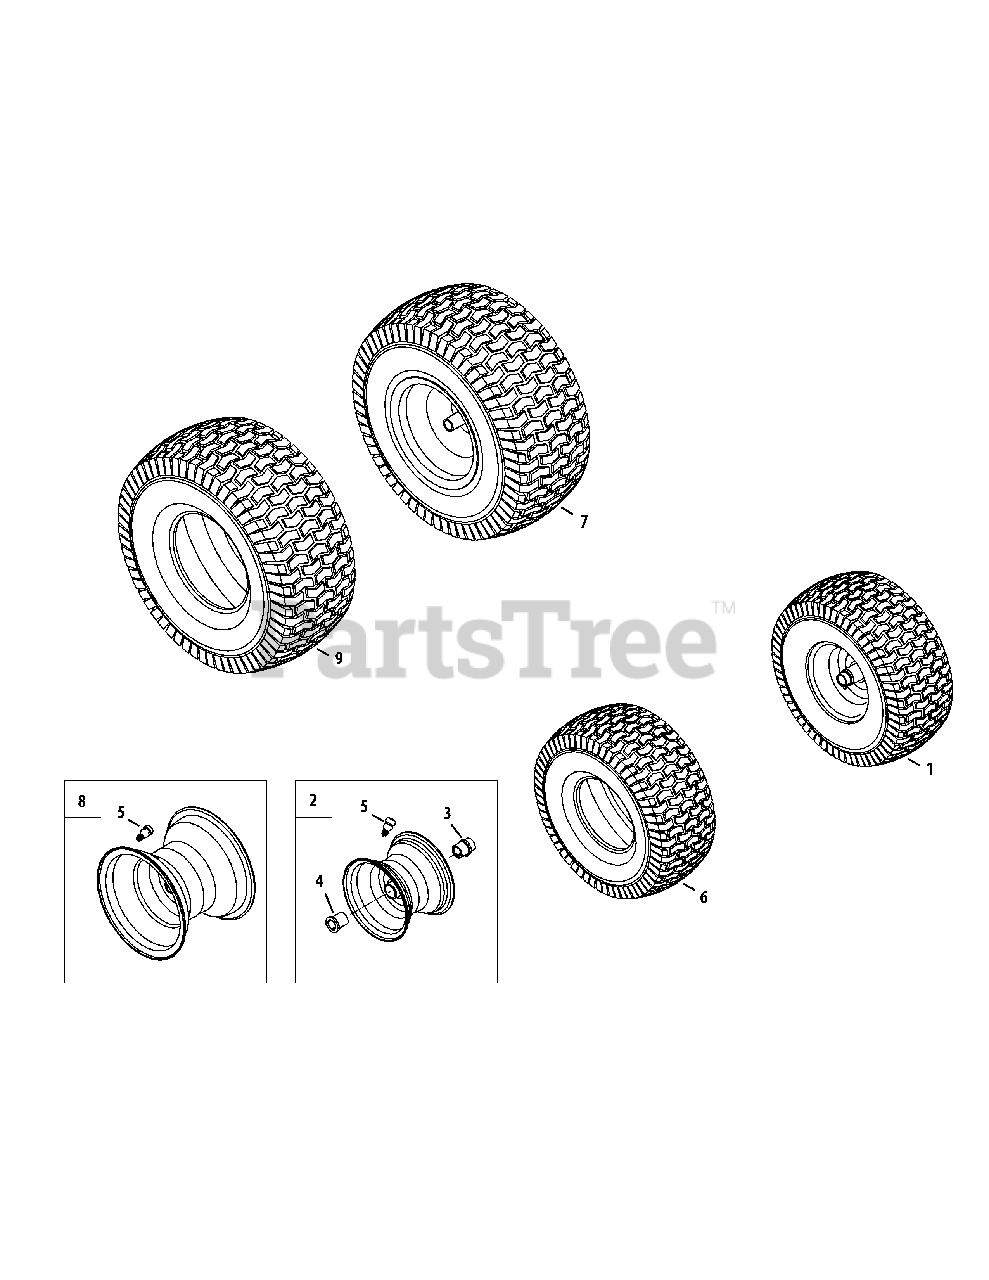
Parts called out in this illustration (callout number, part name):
1	Wheel Ass’y, Complete, 15 x 6 x 6
2	Rim Ass’y, 6.0 x 4.5, Flange Bearings
3	Bearing, Flange, .760 ID w/ Fitting
4	Bearing, Flange, .760 x 1.00 x 1.20
5	Valve, Tubeless Air
6	Tire, 15 x 6 x 6 Sq Shoulder
7	Wheel, Complete, 20 x 8 x 8
8	Rim Ass’y, 8.0 x 7.0 x .750 ID
9	Tire, 20 x 8 x 8 Sq Shoulder
